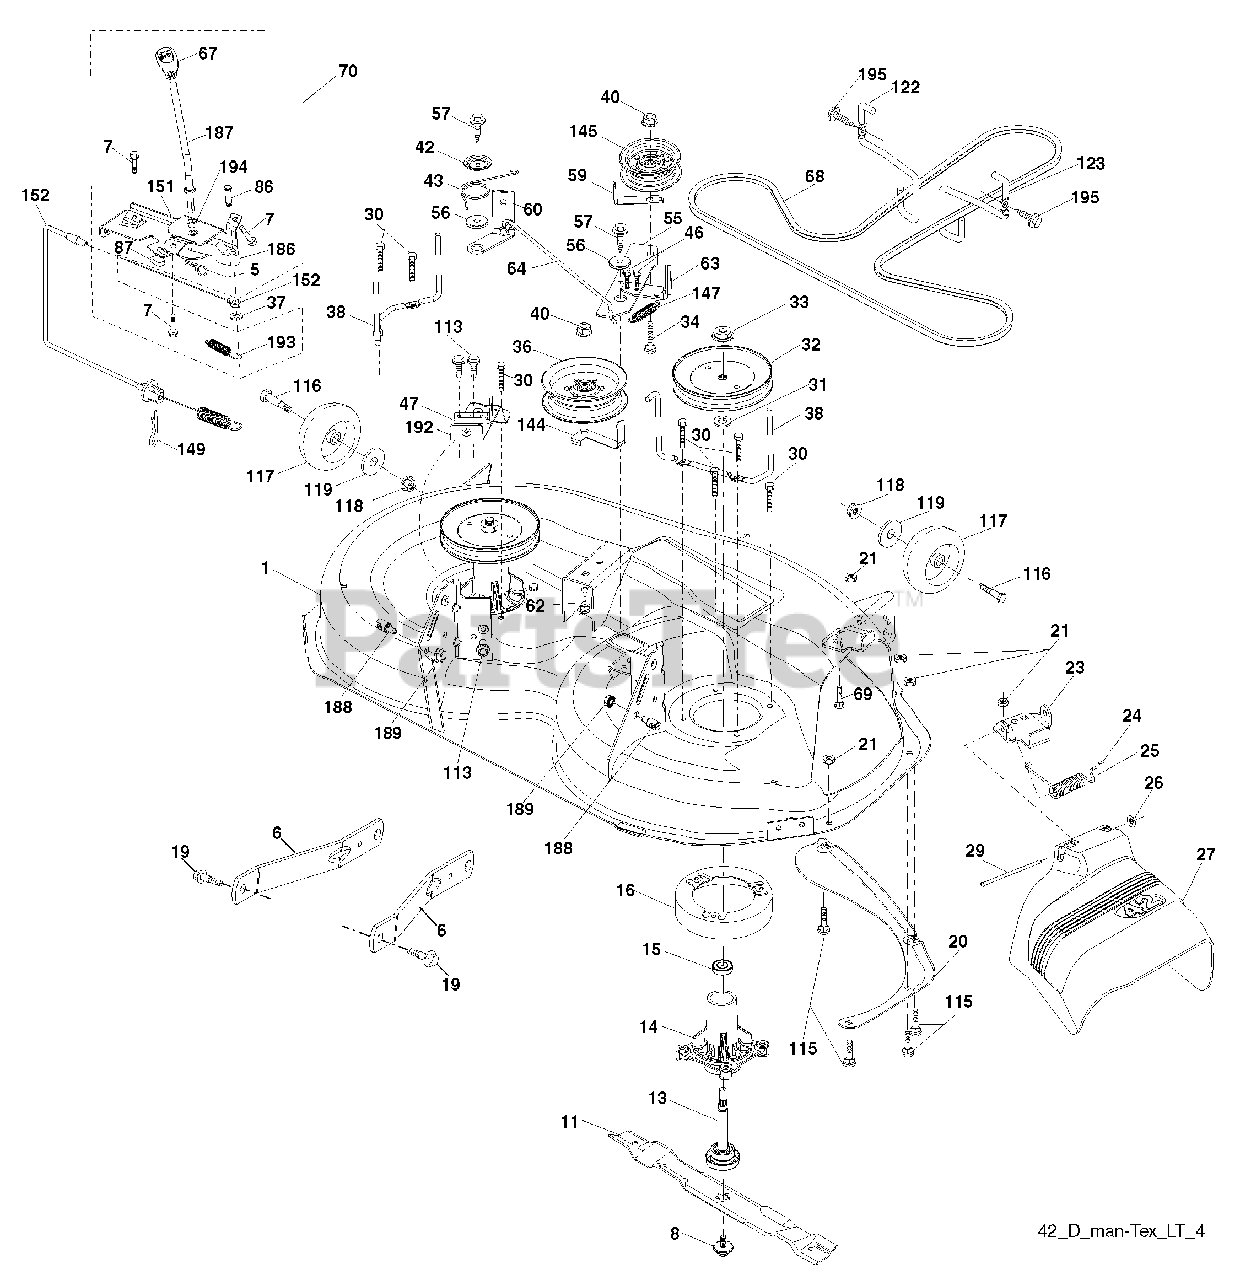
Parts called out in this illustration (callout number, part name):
1	Deck Weldment Mower
5	Retainer Spring
6	Arm Suspension
7	Screw 10 x 3/4 Single Lead Hex
8	Bolt/Washer asm 7/16-20 unf
11	Blade, 42" Hi-Lift (For bagging or discharge)
11	Blade, 42" Mulching Std (For mulching mowers only)
11	Blade, 42" Mulching Premium (For better wear when mulching)
13	Shaft Assembly, Mandrel
14	Housing, Mandrel
15	Bearing, Ball, Mandrel
16	Stripper, Mower Deck
19	Bolt, Shoulder
20	Baffl e, Vortex
21	Nut, Crownlock 5/16-18 unc
23	Bracket, Defl ector
24	Cap, Sleeve
25	Spring, Torsion, Defl ector
26	Nut, Push
27	Shield, Defl ector
29	Rod, Hinge
30	Screw Thdrol Rolling Wsh Hd
31	Washer, Spacer
32	Pulley, Mandrel
33	Nut, Toplock, Flanged
34	Bolt Carr Sh. 3/8-16 x 1-1/2 Gr. 5
36	Pulley, Idler, Flat
37	Washer
38	Keeper Belt LH Mandrel
40	Nut, Lock Flg. 3/8-16 unc
42	Spring Torsion Brake
43	Spring Torsion Retainer
46	Screw Thd Roll 1/4-20 x 5/8
47	Bracket Clutch Cable
54	Washer, Hardened
55	Arm, Idler
56	Spacer, Retainer
57	Screw 3/8-16 x 1
59	Guard, Tuv Idler
60	Arm Brake Mower
62	Bolt Rd Hd Sq Nk 3/8-16 unc x 2
63	Arm Brake Mower
64	Link Brake Asm
65	Spacer Retainer
67	Handle Clutch Cable
68	V-Belt
69	Bolt
70	Clutch Asm Manual
86	Pin Attachment Cable
87	Switch Interlock Clutch Cable
88	Screw 10-24 x 5/8
113	Bolt 5/16-18
115	Bolt Carr. 5/16-18 x 5/8
116	Bolt, Shoulder
117	Wheel, Gauge
118	Nut, Crownlock 3/8-1
119	Washer 13/32 x 7/8 x 14 Ga.
122	Keeper Belt Engine LH
123	Keeper Belt Engine RH
144	Keeper Belt
145	Pulley Idler
147	Spring Return
149	Retainer Spring
151	Bracket Clutch
152	Manual Clutch Cable
186	Arm Actuator
187	Lever Control
188	Stud Fastener
189	Nut Lock Hex Flange
192	Bracket Brake Stand LH
193	Spring Plunger Activator
194	Bearing Control Lever Clutch
195	Screw Hex Wsh Thdr 3/8-16 x 3/4
195	Mandrel Assembly
195	Replacement Mower, Complete
